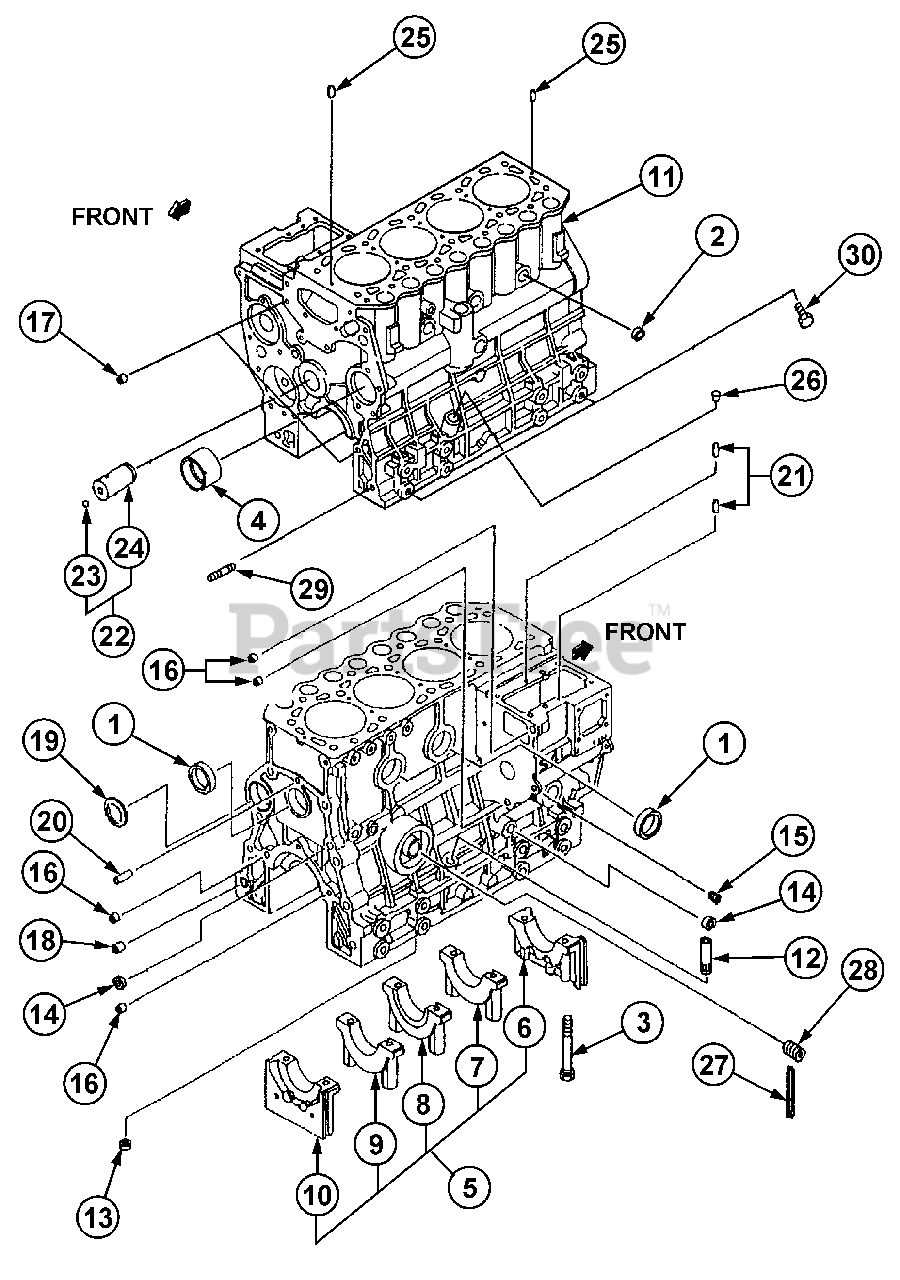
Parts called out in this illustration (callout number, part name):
4	Bush, Camshaft
5	Cap Set, Metal
6	Cap, Metal Flont
10	Cap, Metal Rear
11	Block, Cylinder
12	Guide, Oil Level
13	Cap, Sealing (12)
14	Cap, Sealing (14)
15	Plug, Taper
16	Bushing, Knock
17	Bushing, Knock
18	Bushing, Knock
19	Plug, Expansion
22	Shaft Assy, Idle
24	Shaft, Idler
26	Plug, Taper
28	Shaft, Oil Filter
